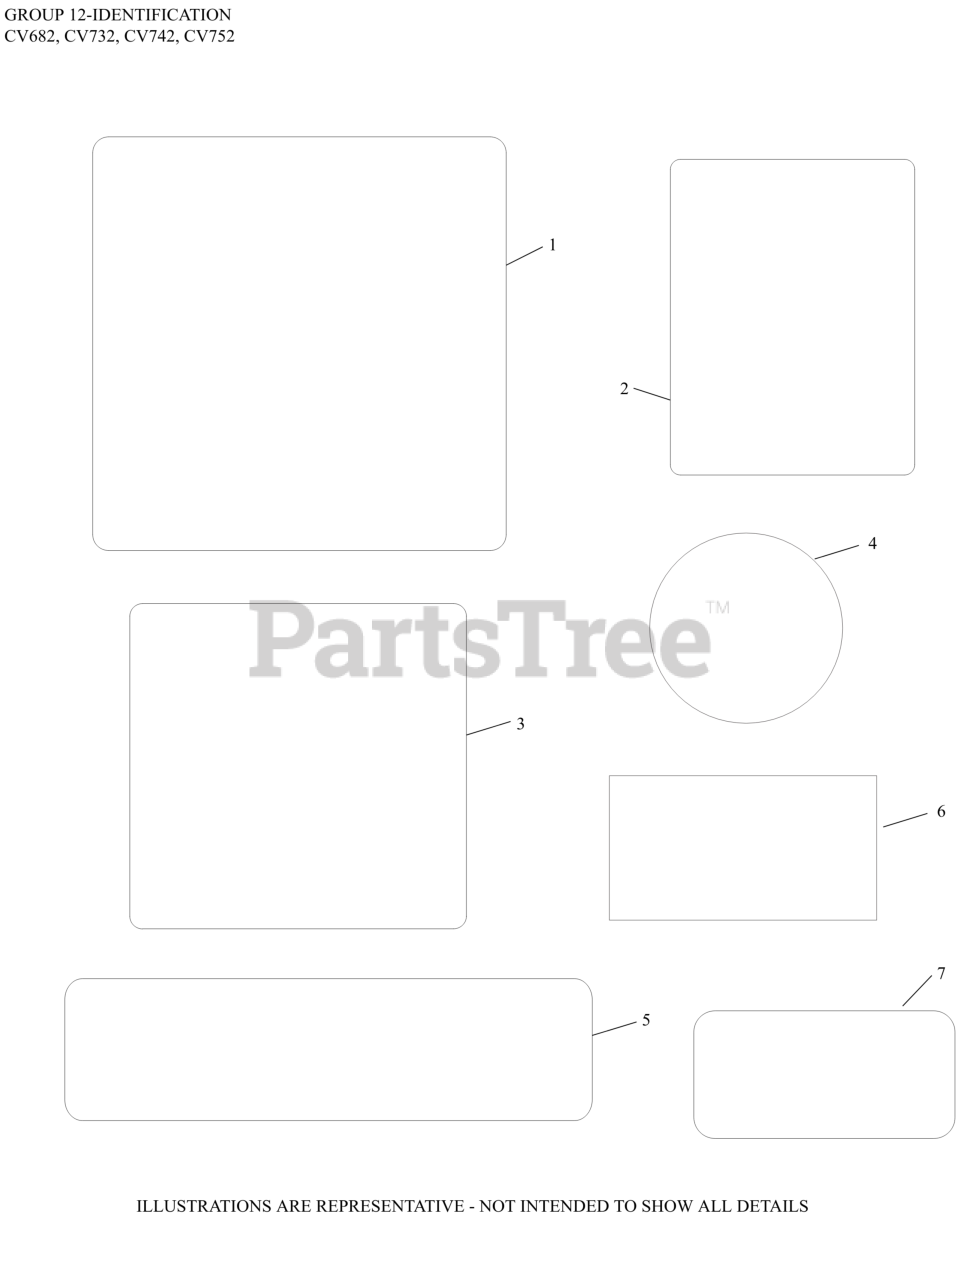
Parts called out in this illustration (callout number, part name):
2	LABEL, CLEAR LAMINATION
3	DECAL HDAC, 27.0 HP/CV-CH752/747cc
6	DECAL, USA
